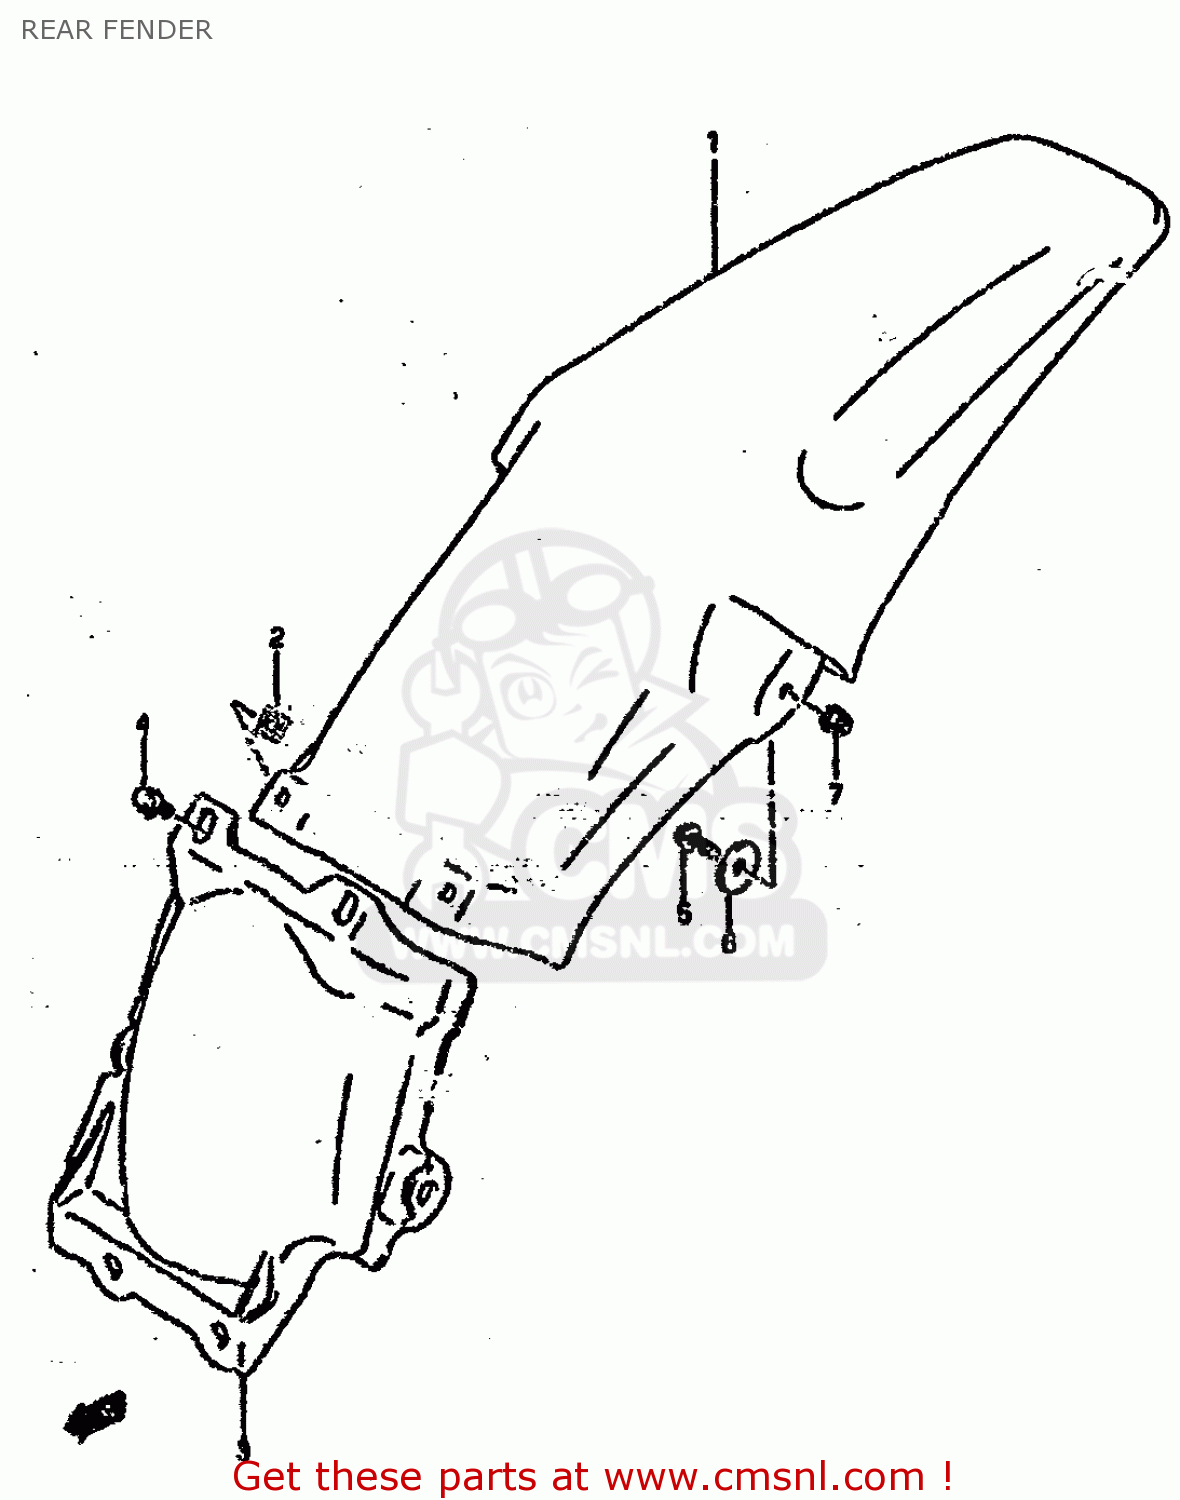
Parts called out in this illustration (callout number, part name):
1	BODY,RR FENDER RR
2	NUT,RR FENDER
3	BODY,RR FENDER FR
4	BOLT
5	BOLT
6	WASHER (6.5X29X1.6)
7	NUT
